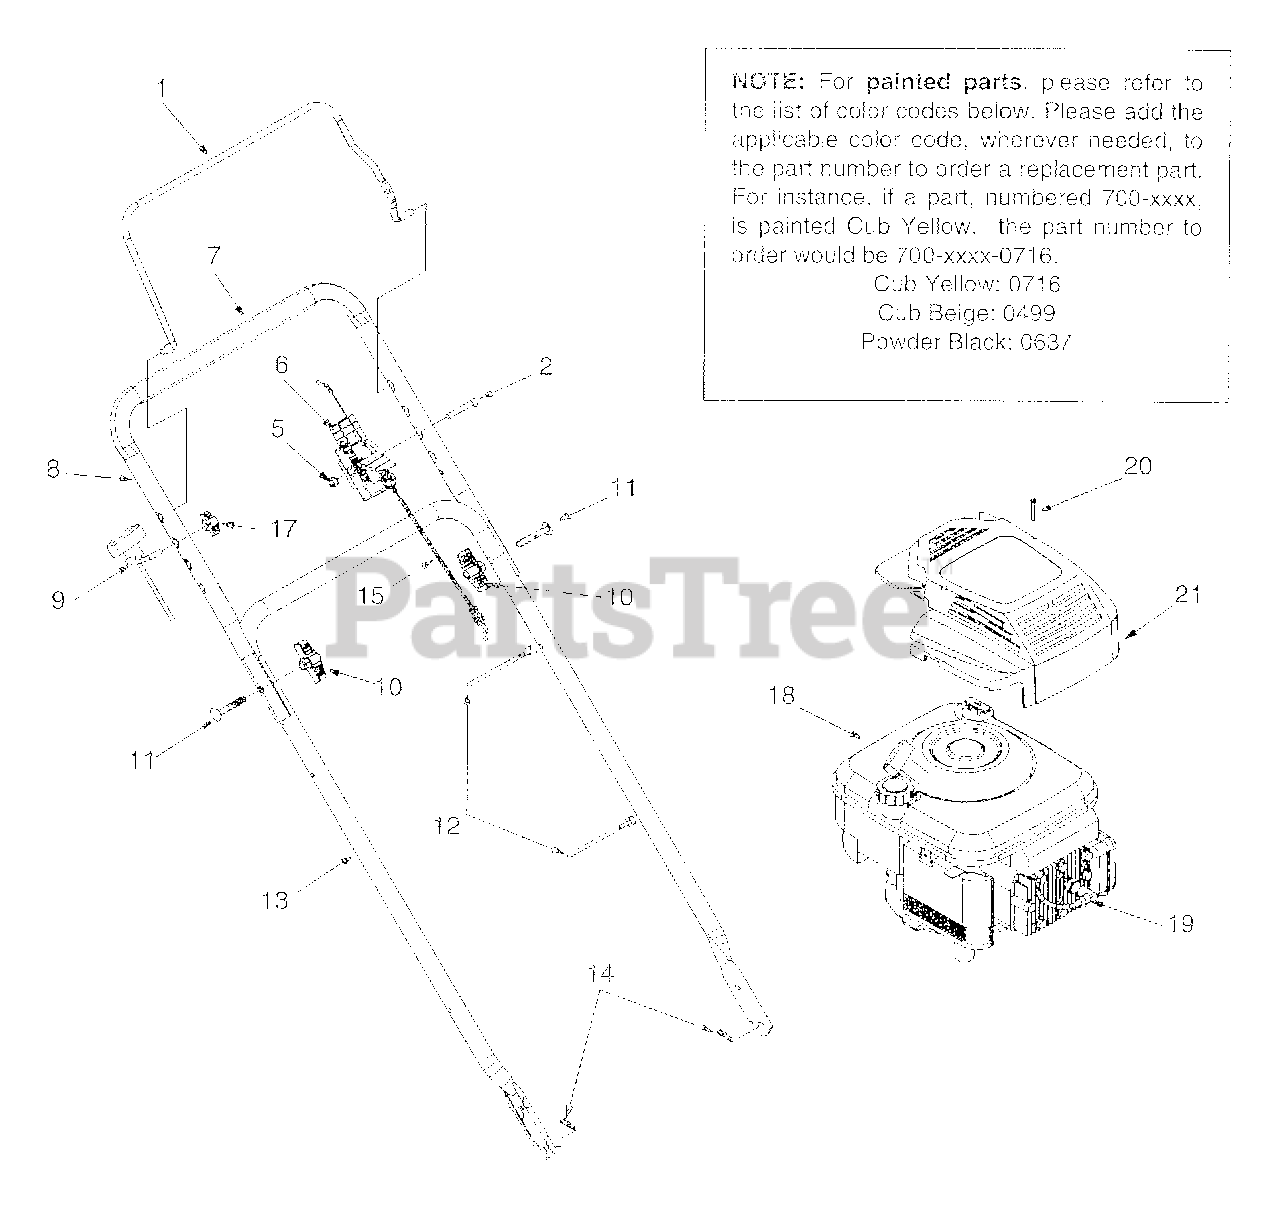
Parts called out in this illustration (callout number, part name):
1	Control Handle Ass'y.
2	Oval C-Sunk Screw
5	Hex Lock Nut
6	Control Housing
7	Foam Grip
10	Hand Knob
11	Carriage Bolt
12	Cable Tie
14	Hairpin Clip
15	Control Cable 40.5" Lg.
17	Handle Knob
18	Engine
19	Spark Plug Boot
20	Screw #10-32 x 2.3" Lg.
21	Engine Shroud
